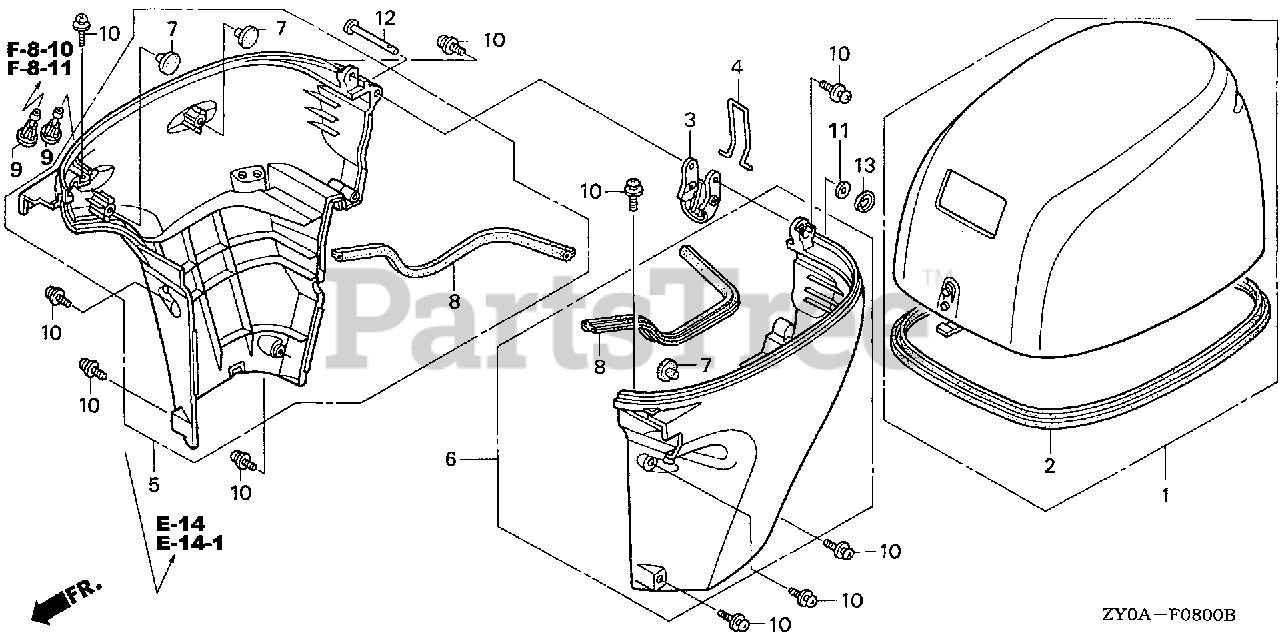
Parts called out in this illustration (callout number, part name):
1	COVER, ENGINE *NH282MU* (OYSTER SILVER METALLIC-U)
2	SEAL, ENGINE COVER
3	LEVER, FASTENER
4	WIRE, FASTENER (3.2)
5	COVER, R. ENGINE (LOWER) *NH282MU* (OYSTER SILVER METALLIC-U)
6	COVER, L. ENGINE (LOWER) *NH282MU* (OYSTER SILVER METALLIC-U)
7	RUBBER, CUSHION
8	SEAL, COVER (LOWER)
9	GROMMET, WATER CHECK
10	BOLT-WASHER, SOCKET (5X10)
11	WASHER, PLAIN (5MM)
12	PIN (5X47)
13	RING, STOPPER
